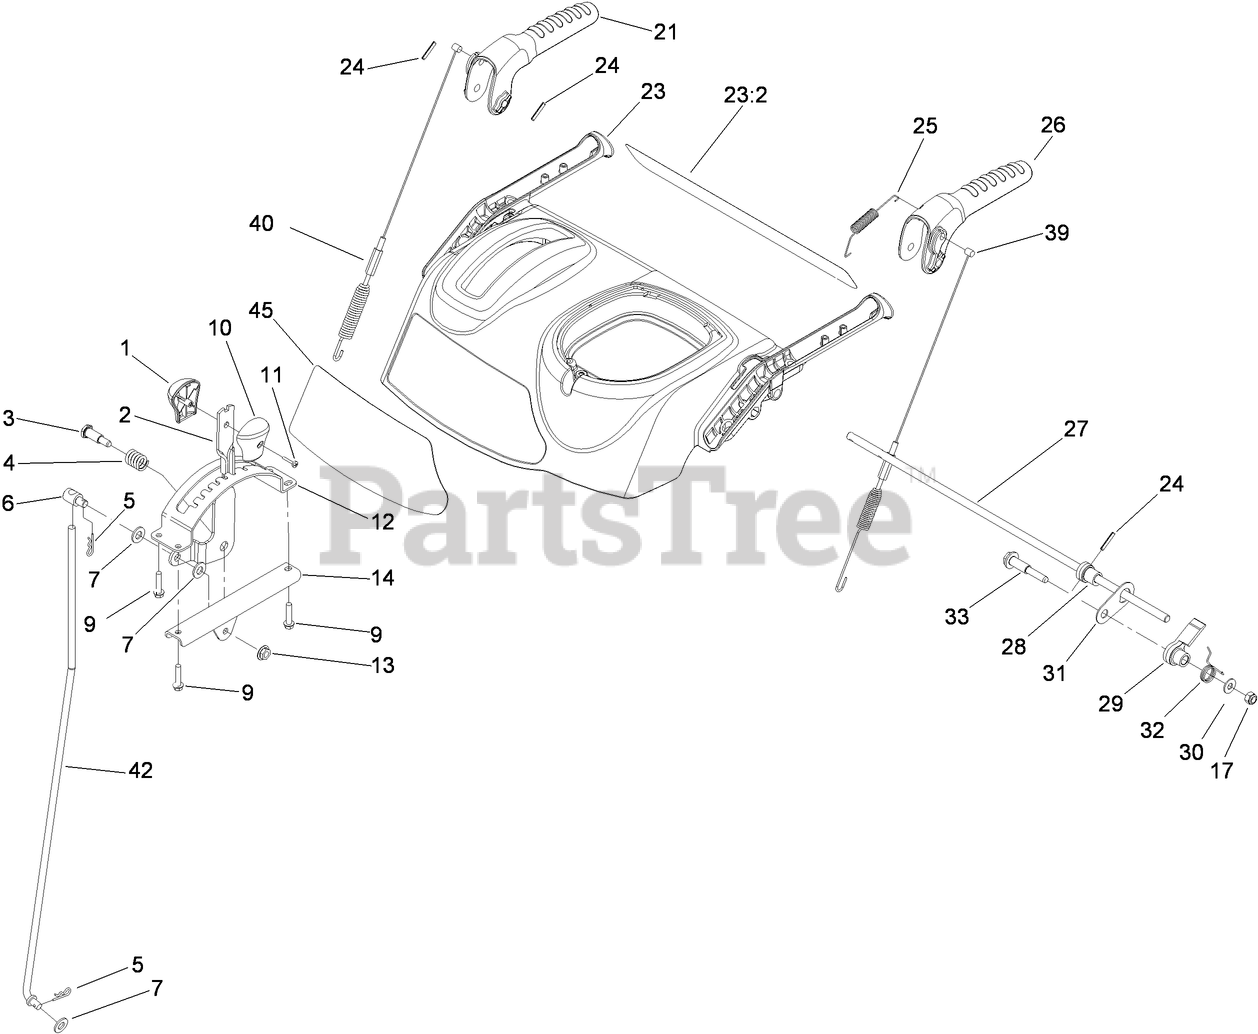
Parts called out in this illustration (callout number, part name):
1	KNOB-SHIFT, RH
2	SELECTOR-SPEED
3	SCREW-SHOULDER
6	TRUNNION-ROD
7	WASHER-FLAT
9	SCREW-PLASTITE
10	KNOB-SHIFT, LH
11	SCREW-PPH
12	GUIDE-SELECTOR, SPEED
13	NUT-HF
14	MOUNT-SELECTOR, SPEED
17	NUT-LOCK, NI
21	LEVER-AUGER
23	CONTROL PANEL ASM
23:2	DECAL-PANEL, CONTROL
24	PIN-SPRING
25	SPRING-TENSION
26	LEVER-TRACTION
27	ROD-LOCKOUT
28	CAM-LOCKOUT
29	LATCH-LOCKOUT
30	WASHER-FLAT
31	LINK-LOCKOUT
32	SPRING-TORSION
39	CABLE-TRACTION
40	CABLE-AUGER
45	DECAL-CONTROL PANEL
